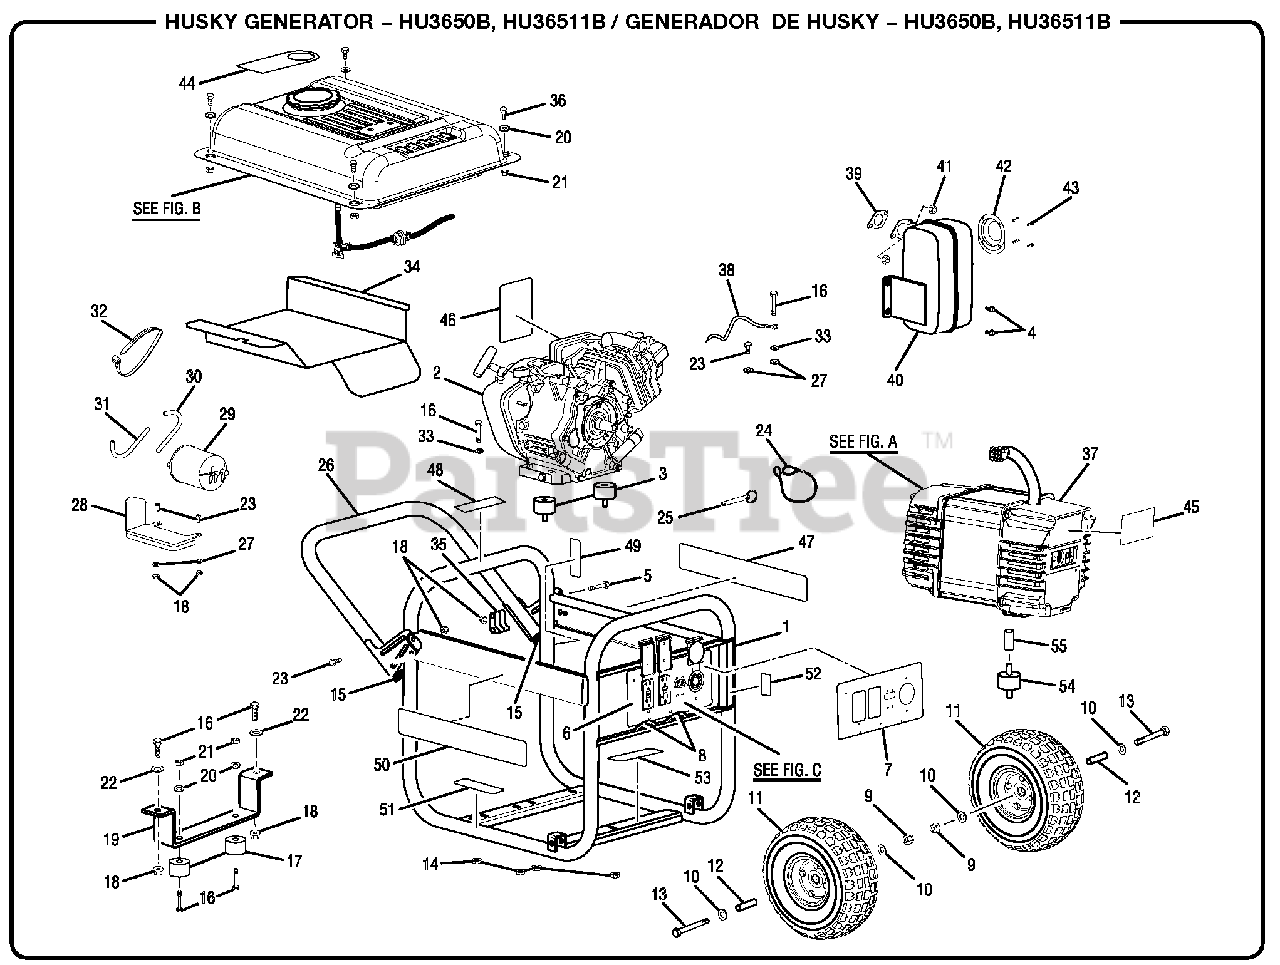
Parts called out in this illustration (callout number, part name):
1	Carrier Assembly
2	Engine (Subaru OHC)
4	Bolt (5/16-24 x 5/8 in.)
5	Bolt (5/16-18 x 2-1/4 in., Hex Hd.)
6	Control Panel
7	Control Panel Label
8	Cord Retainer
9	Lock Nut (3/8-16)
10	Washer (3/8 in.)
12	Spacer (3/8 in. ID)
13	Bolt (3/8-16 x 4-1/4 in.)
14	Lock Nut (5/16-18)
16	Bolt (5/16-18 x 1-1/2 in.)
17	Rubber Foot
18	Flange Nut (5/16-18)
19	Foot Bracket
20	Washer (1/4 in.)
21	Lock Nut (1/4-20)
22	Washer (5/16 in.)
23	Bolt (5/16-18 x 3/4 in., Hex Hd.)
25	Release Pin
27	External Star Washer (5/16 in.)
28	Bracket
29	Canister
30	Purge Hose
31	Rollover Hose
32	Cable Tie (18.6 in.)
33	Lock Washer (5/16 in.)
34	Heat Shield
35	Handle Bracket Spacer
36	Bolt (1/4-20 x 1 in.)
37	Generator Head Assembly
38	Ground Wire Assembly
41	Hex Nut (8 mm)
42	Spark Screen
43	Screw (#8 x 3/8 in.)
44	Danger Hang Tag
45	Data Label
46	Start Label
47	Danger Label
48	Fire Danger Label
49	Lock Pin Label
50	Logo Label
51	Engine Lubricant Label
52	Hot Surface Label
53	Ground Warning Label
55	Spacer (3/8 in. ID)
